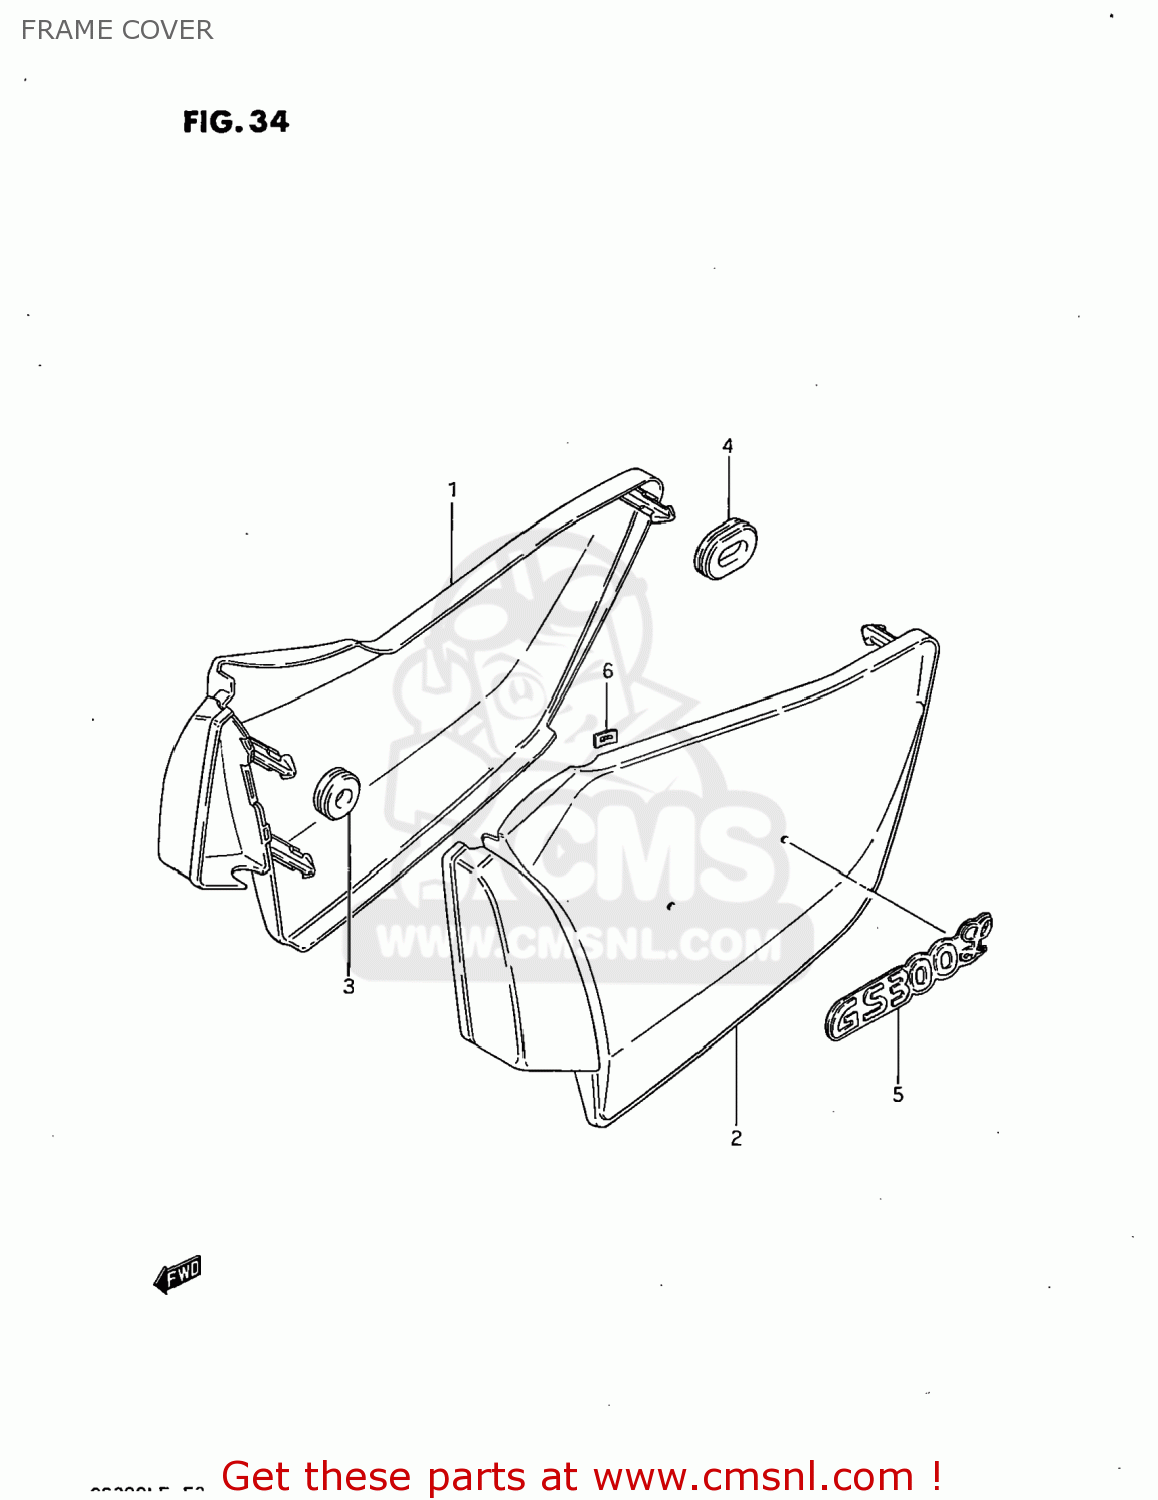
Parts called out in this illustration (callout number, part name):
1	COVER,FRAME,RIGHT
2	COVER,FRAME,LEFT
3	CUSHION
4	CUSHION
5	EMBLEM,FRAME COVER
6	NUT
